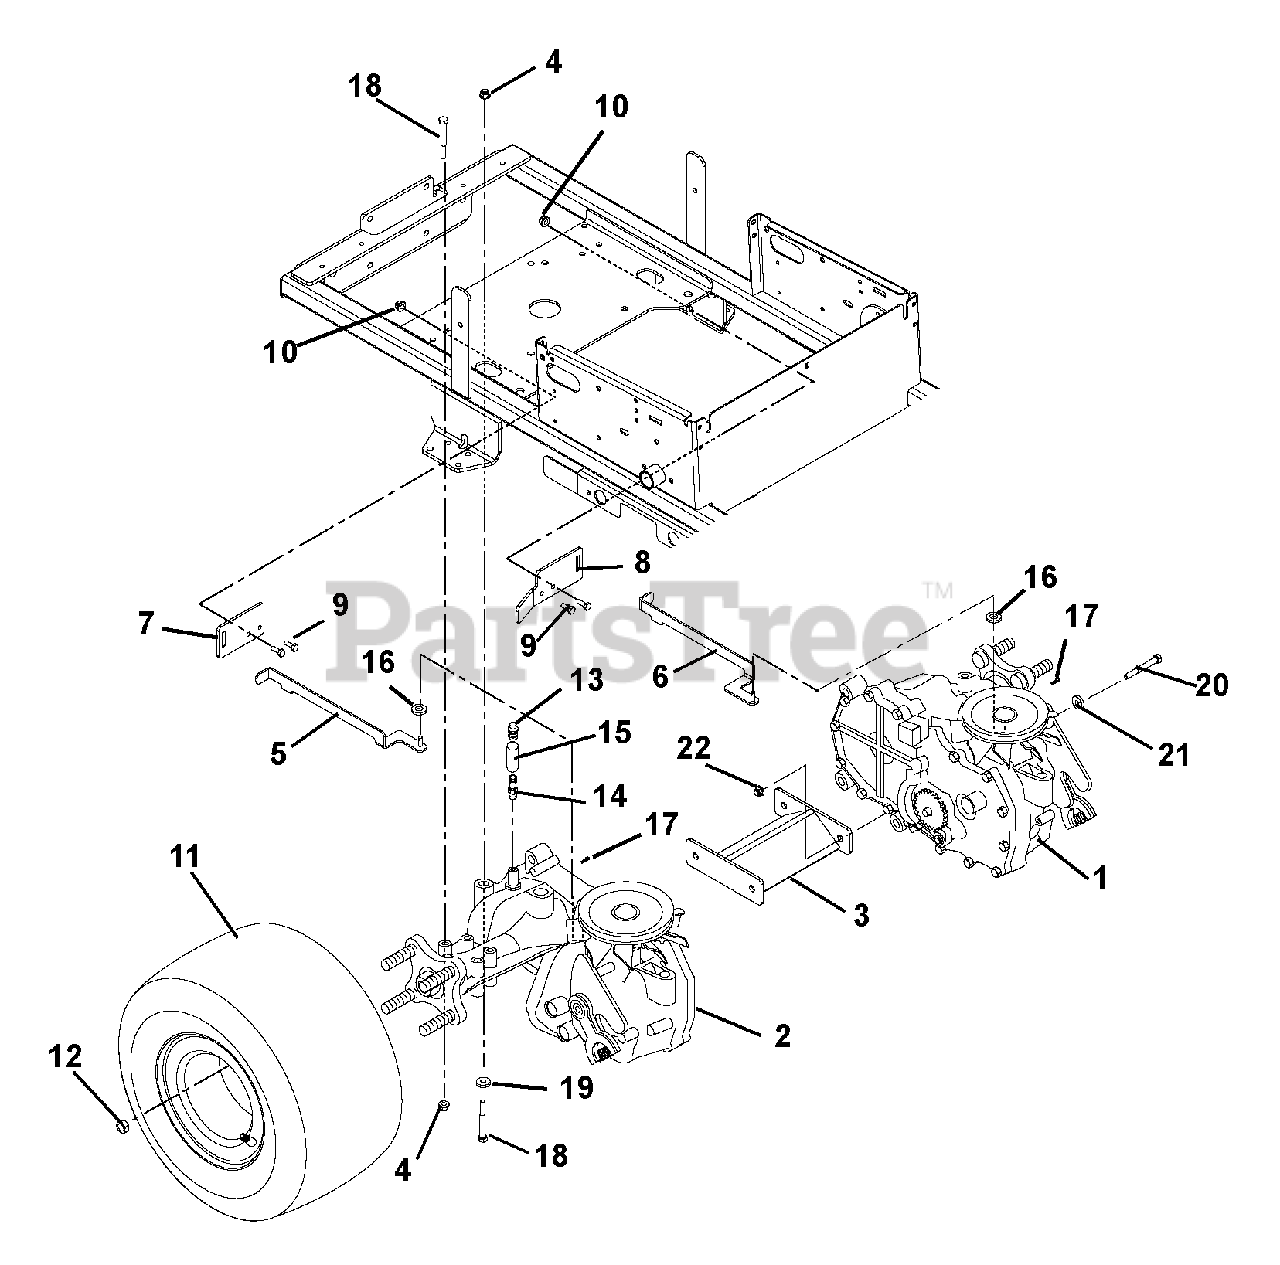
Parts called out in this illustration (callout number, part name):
1	EZT, LH TRANSAXLE (ZOOM)
2	EZT, RH TRANSAXLE (ZOOM)
3	WMT, TRANSAXLE SUPPORT
4	@NUT-LK-NYL-FLG .31-18 YWZC
5	WMT, DUMP VALVE (ZOOM-RH)
6	WMT, DUMP VALVE (ZOOM-LH)
7	BRACKET, DUMP VALVE
8	BRKT,DUMP VALVE/CLUTCH STOP
9	@BLT-HEX .25-20X.75 GR5 YWZC
10	NUT-LUG .50-20 YWZC
11	ASSY-TIRE 9.5X18-2PLY
12	NUT-LUG .50-20 YWZC
13	CAP-VENT .50
14	FTG-STR .50 O-RING
15	HOSE - VENT
16	WSHR-FL-STL .265X.50X.087YWZC
17	PIN-HAIR INT .06X.18X.77
18	@BLT-HEX .31-18X2.75 GR5 YWZC
19	WSHR-FL-STL .328X.87X.179 YWZC
20	@BLT-HEX .38-16X2.50 GR5 YWZC
21	WSHR-FL-STL .406X1.00X.188 YWZ
22	@NUT-LK-NYL-FLG .38-16 YWZC
